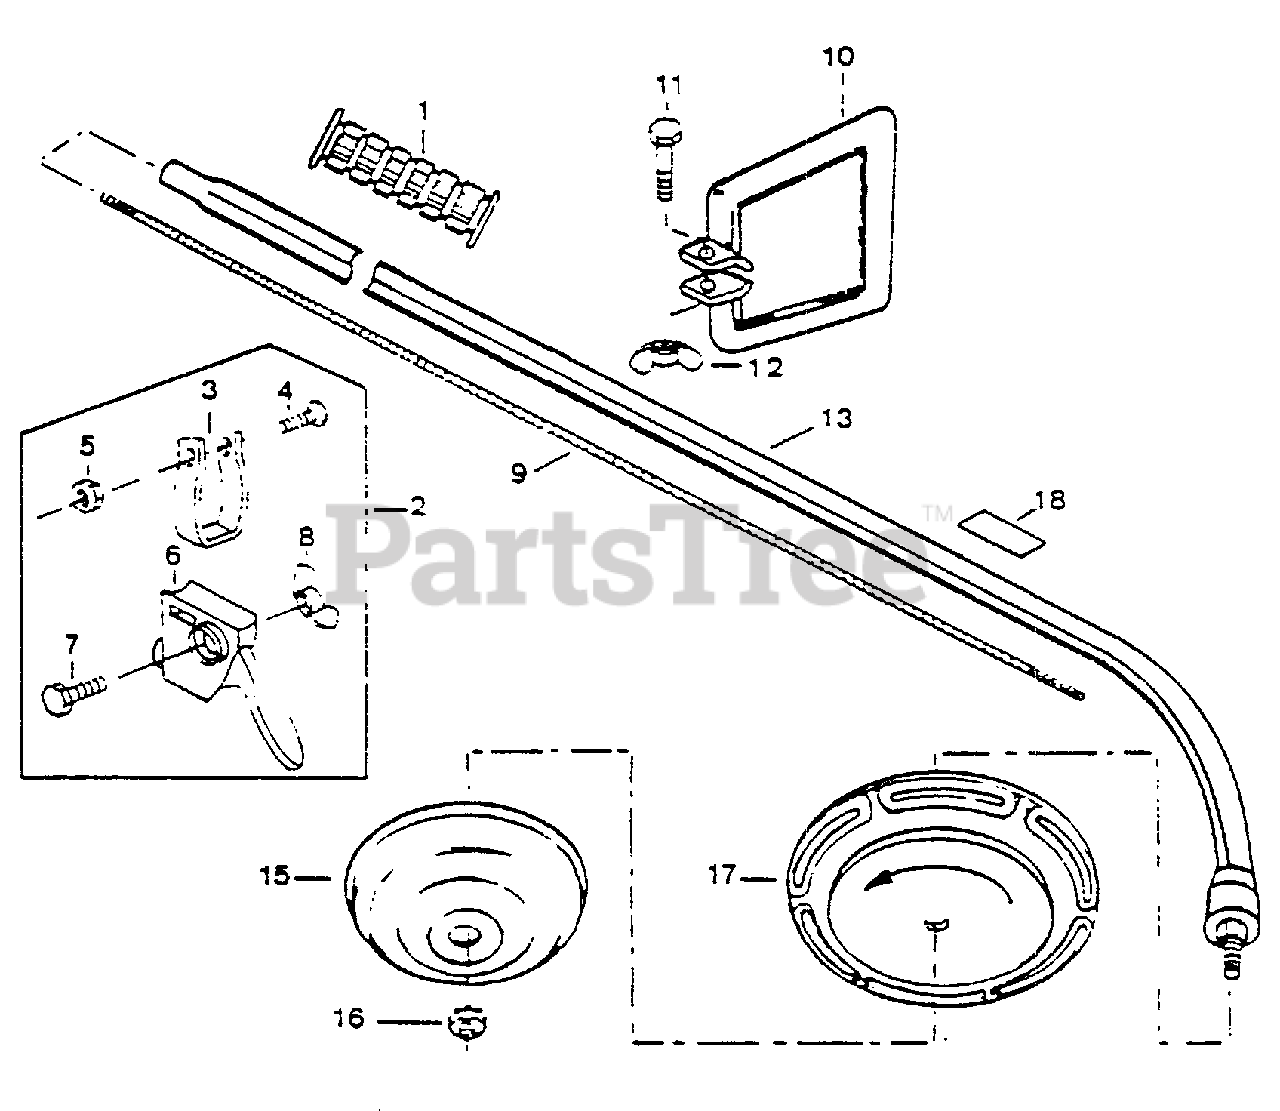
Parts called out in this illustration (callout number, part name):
2	CONTROL CABLE ASSY
3	CLAMP, THROTTLE
4	SCREW - 10-32
5	NUT - 10-32
6	Lever Throttle w/Body
7	SCREW - 10-32 X 1"
8	WINGNUT - 50-32
9	DRIVESHAFT - FLEXIBLE
10	Guide Handle
11	SCREW - 1/4-20
12	WINGNUT - 1/4-20
13	DRIVESHAFT ASSY - LEFT
14	Mono-Head w/.080 line complete
15	LID
16	SCREW - 1/4-20
17	Head Body Mono-Head
18	LABEL - LUBRICATION
